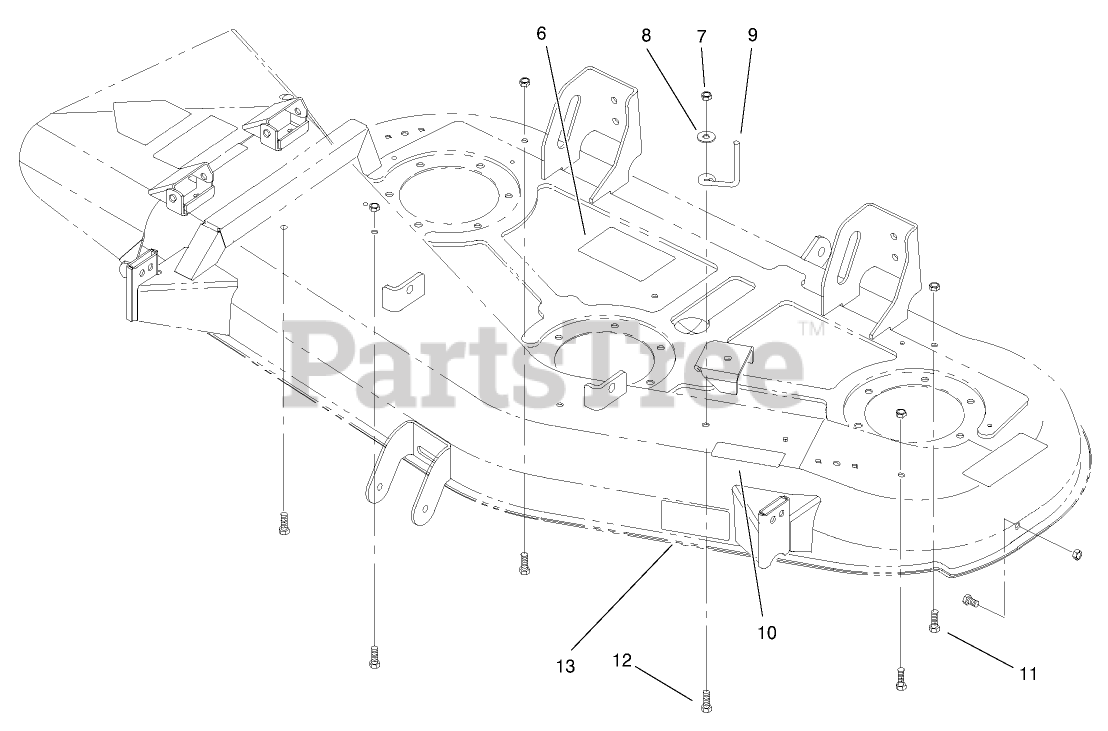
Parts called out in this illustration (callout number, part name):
6	DECAL-BELT ROUTING
7	NUT-LOCK, NI
8	WASHER-PLAIN
9	GUIDE-BELT
10	DECAL-BELT ROUTING
11	SCREW-HH
12	SCREW-HH
13	DECAL-ADJUSTMENT, WHEEL
